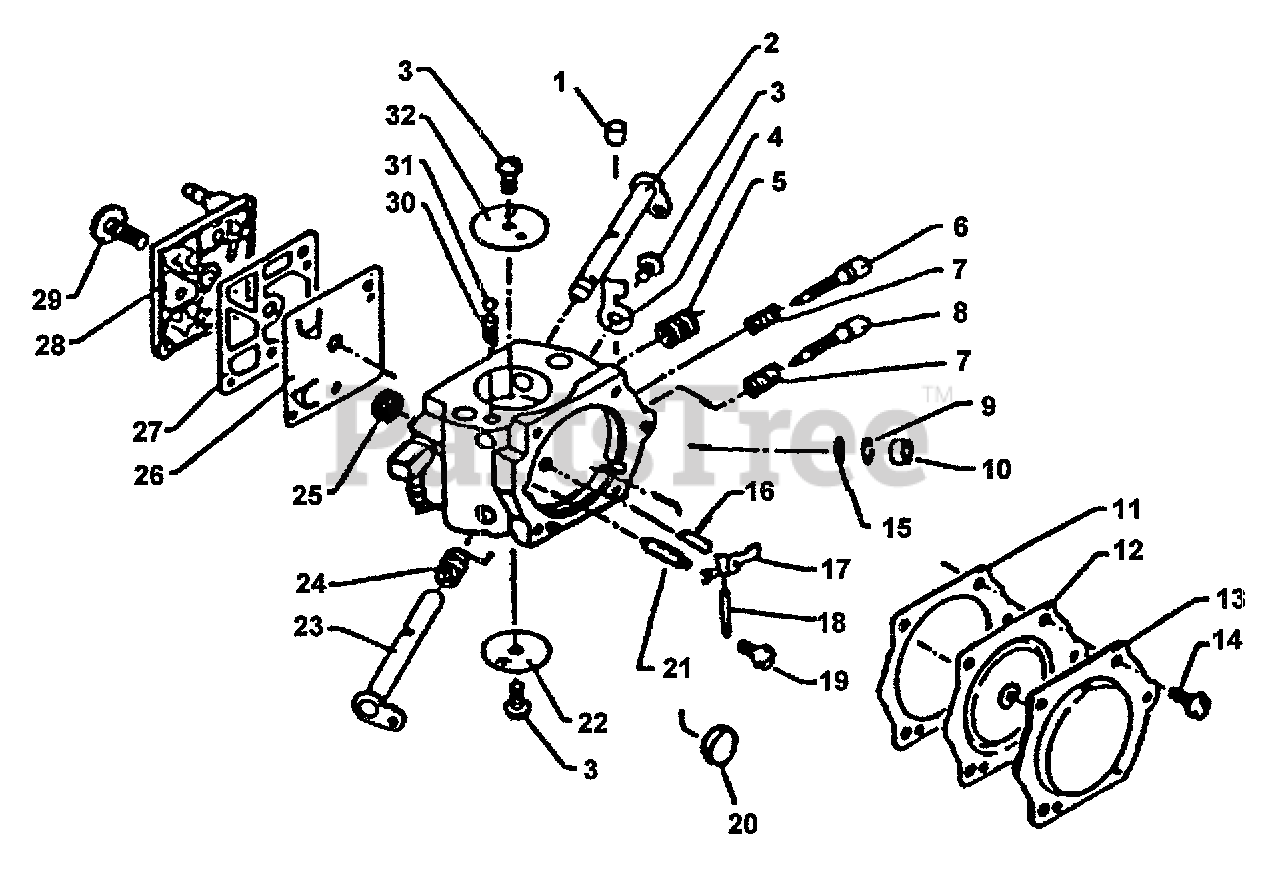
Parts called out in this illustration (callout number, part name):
2	SHAFT, CHOKE
4	STOP, THROTTLE
5	SPRING, IDLE ADJUST
6	NEEDLE - LOW SPEED
7	SPRING
8	NEEDLE - HIGH SPEED
9	RING, RETAINING
10	PLUG, WELCH
11	GASKET, METERING
12	DIAPHRAGM, METERING
13	COVER, METERING
14	SCREW
15	STRAINER
16	SPRING, METERING LEVER
17	LEVER, METERING
18	PIN, METERING LEVER
19	SCREW, METERING LEVER PIN
20	PLUG, WELCH
21	VALVE, INLET NEEDLE
22	VALVE, THROTTLE
23	SHAFT, THROTTLE
24	SPRING, THROTTLE RETURN
25	STRAINER
26	DIAPHRAGM, PURGE
27	GASKET, PURGE
28	COVER, PUMP
29	SCREW, PUMP COVER
31	BALL, CHOKE
32	VALVE, CHOKE
